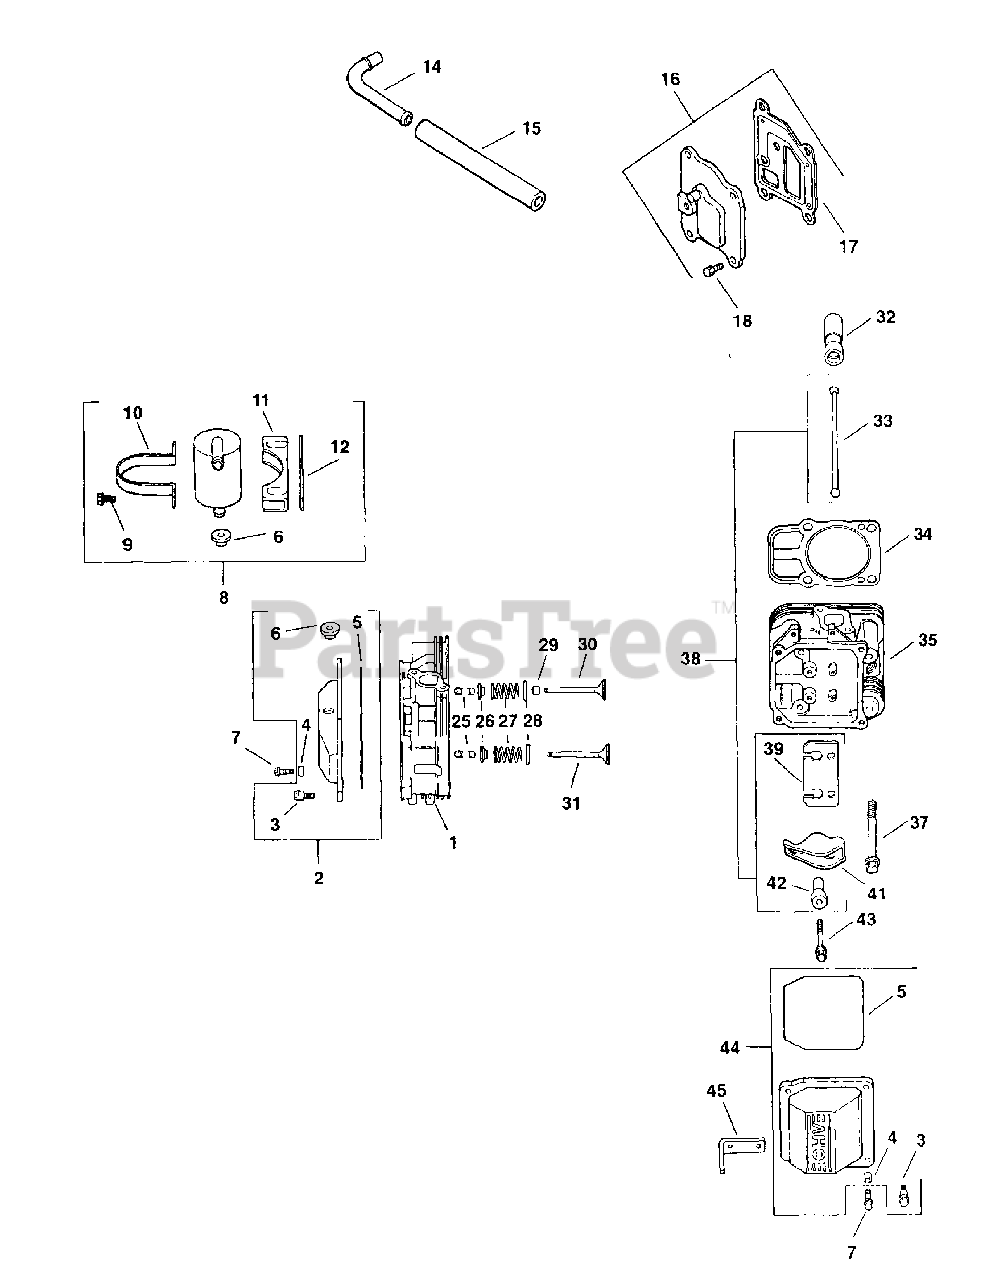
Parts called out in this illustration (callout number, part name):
1	Head Assembly, #1 Cylinder
2	Kit, Valve Cover-Breather
3	Screw, Hex Cap
4	Spacer
6	Grommet, Rubber
7	Screw, Hex Flange
8	Kit, Breather Separator
9	Screw, Hex Cap
10	Strap, Breather
11	Bracket, Breather Separator
15	Hose, Breather
16	Kit, Breather Cover w/Gasket
17	Gasket Breather
18	Screw, Hex Flange
25	Kit, Retainer
26	Cap, Valve Spring
27	Spring, Valve
28	Retainer, Spring
29	Seal, Valve Stem
30	Valve, Intake (Std.)
30	Valve, Intake (.25)
31	Valve, Exhaust (Std.)
31	Valve, Exhaust (.25)
32	Lifter, Valve
33	Rod, Push
34	Gasket, Cylinder Head
35	Head Assembly, #2 Cylinder
37	Screw, Hex Flange
38	Kit, Valve Train
39	Plate, Guide
41	Arm, Rocker
42	Pivot, Rocker Arm
43	Screw, Hex Flange
44	Kit, Valve Cover-Plain
45	Strap, Lifting
